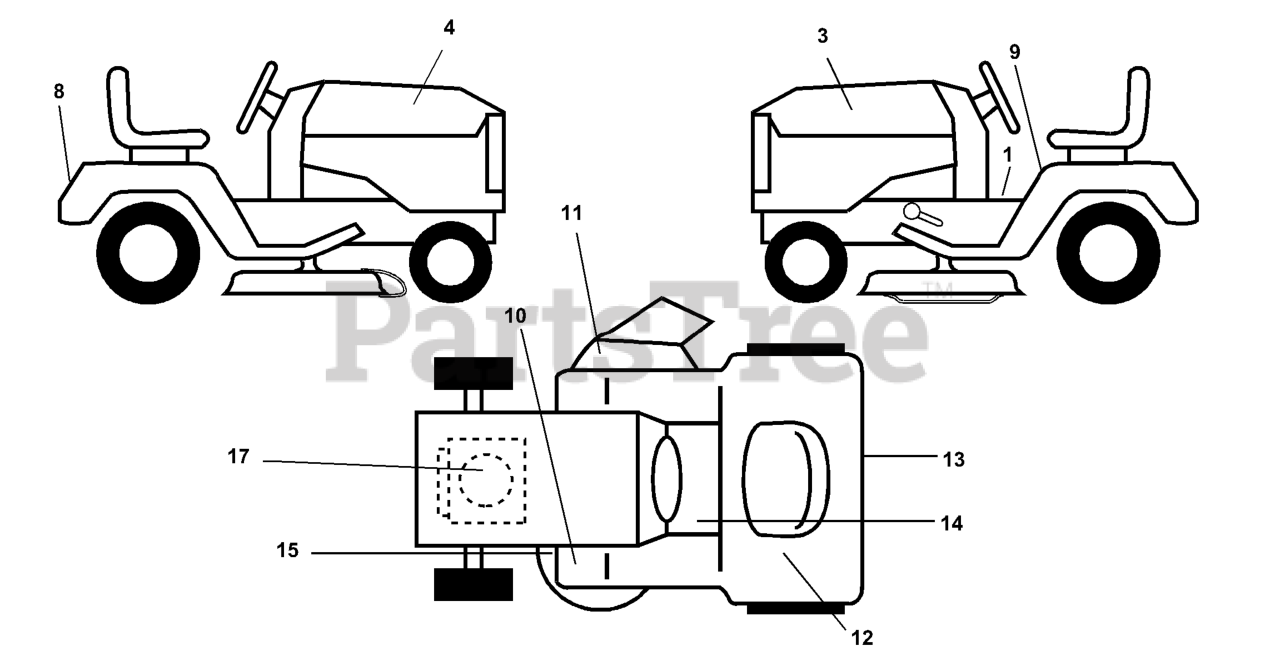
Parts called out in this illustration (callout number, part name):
1	DECAL DASH
3	DECAL HOOD LH
4	DECAL HOOD RH
8	DECAL FENDER HUSQ
9	DECAL CAUTION
11	DECAL WARNING (ENGLISH/FRENCH)
12	DECAL, BATTERY DANGER
13	DECAL DRAWBAR CONTROL
15	DECAL V-BELT SCHEMATIC
17	DECAL HP ENGINE
